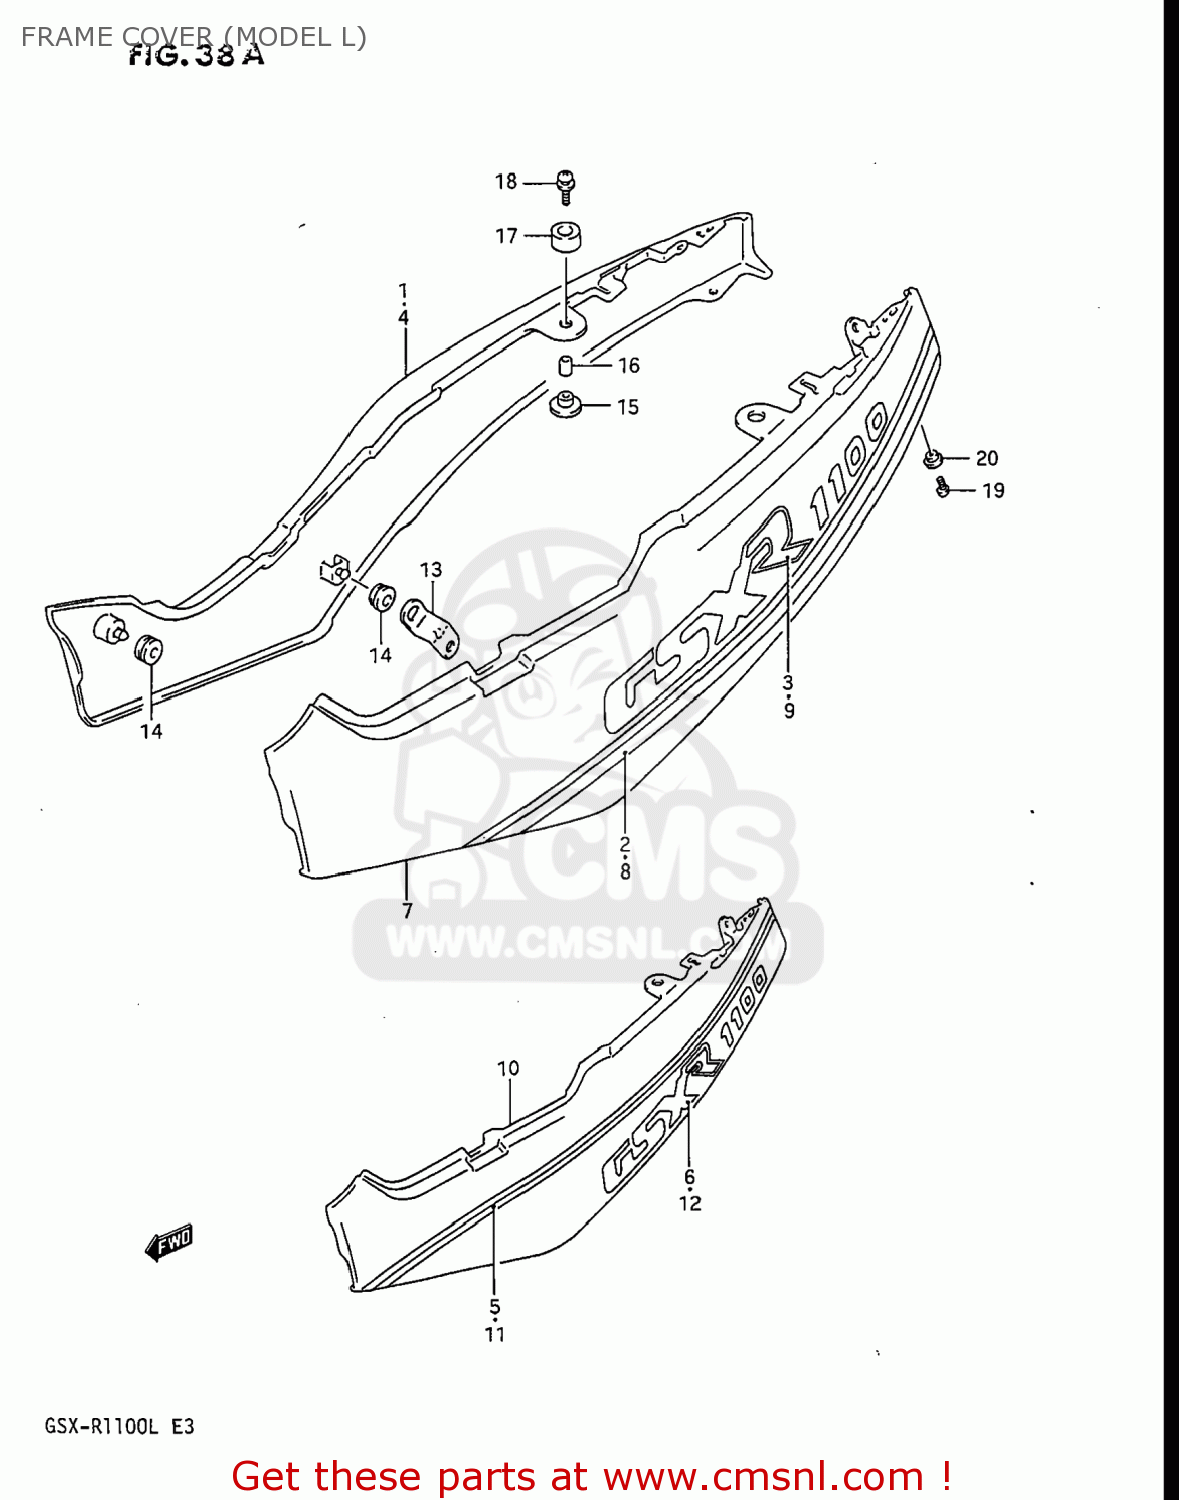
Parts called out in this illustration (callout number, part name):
1	COVER,FRAME,RIGHT
2	TAPE,FRAME COVER STRIPE
3	EMBLEM,FRAME COVER
4	COVER,FRAME,RIGHT
5	TAPE,FRAME COVER STRIPE
6	EMBLEM,FRAME COVER
7	COVER,FRAME,LEFT
8	TAPE,FRAME COVER STRIPE
9	EMBLEM,FRAME COVER
10	COVER,FRAME,LEFT
11	TAPE,FRAME COVER STRIPE
12	EMBLEM,FRAME COVER
13	BRACKET,FRAME COVER
14	CUSHION
15	CUSHION,FRAME COVER LWR
16	SPACER
17	CUSHION,TAIL COVER UPR
18	SCREW(6X30)
19	SCREW, FRONT & REAR
20	WASHER(5.2X14X1.5)
